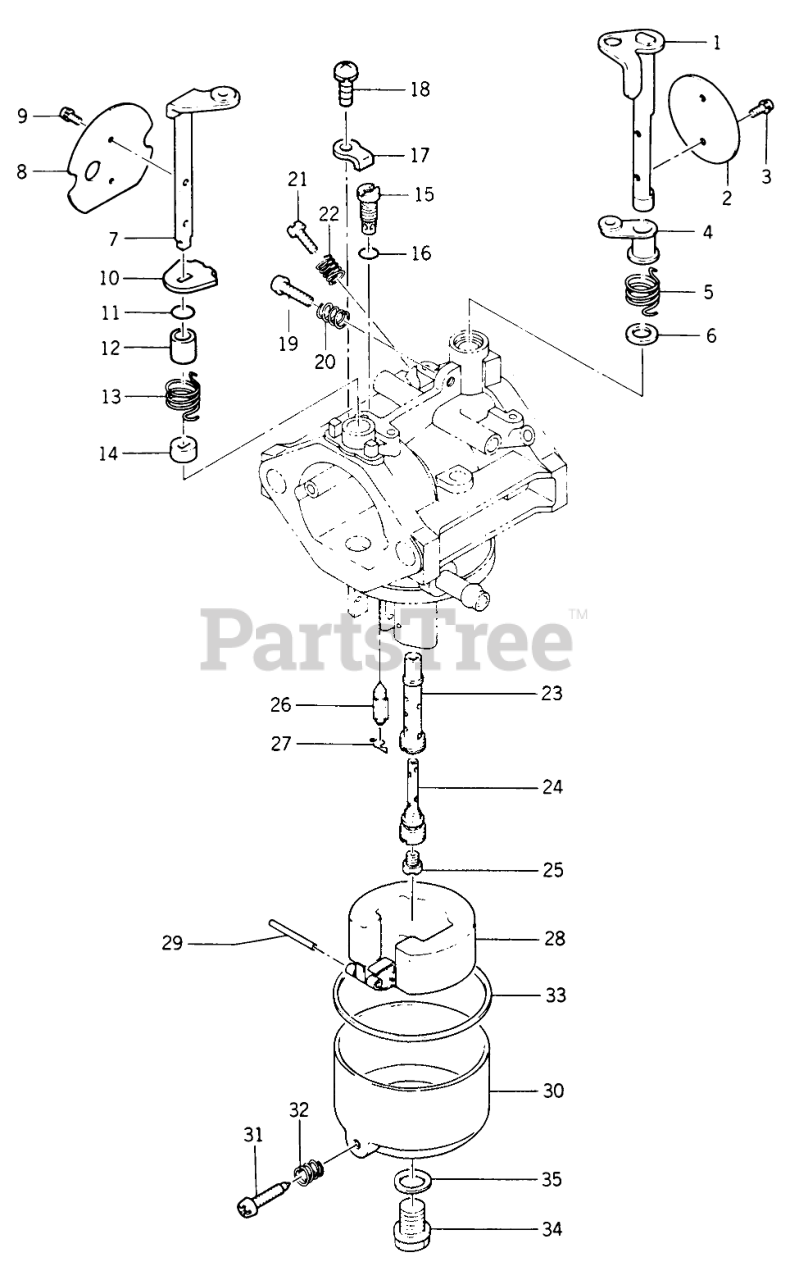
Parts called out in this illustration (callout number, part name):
1	SHAFT THROTTLE
2	VALVE THROTTLE
3	SCREW-THROTTLE PLATE
4	RING BUSHING
5	SPRING
6	Seal
7	SHAFT CHOKE
8	VALVE CHOKE
9	SCREW
10	COLLAR
13	SPRING
14	COLLAR
15	HOLDER-MAIN JET
16	O-RING
17	PLATE
18	SCREW
19	Screw 4 x 14
20	SPRING
21	SCREW PILOT AIR
22	SPRING
23	NOZZLE-MAIN
24	HOLDER-MAIN JET
25	JET-MAIN
26	NEEDLE VALVE ASSY
28	FLOAT
29	PIN-FLOAT
30	ASS'Y-FLOAT CHAMBER
31	SCREW-DRAIN
32	SPRING
33	GASKET
35	GASKET
